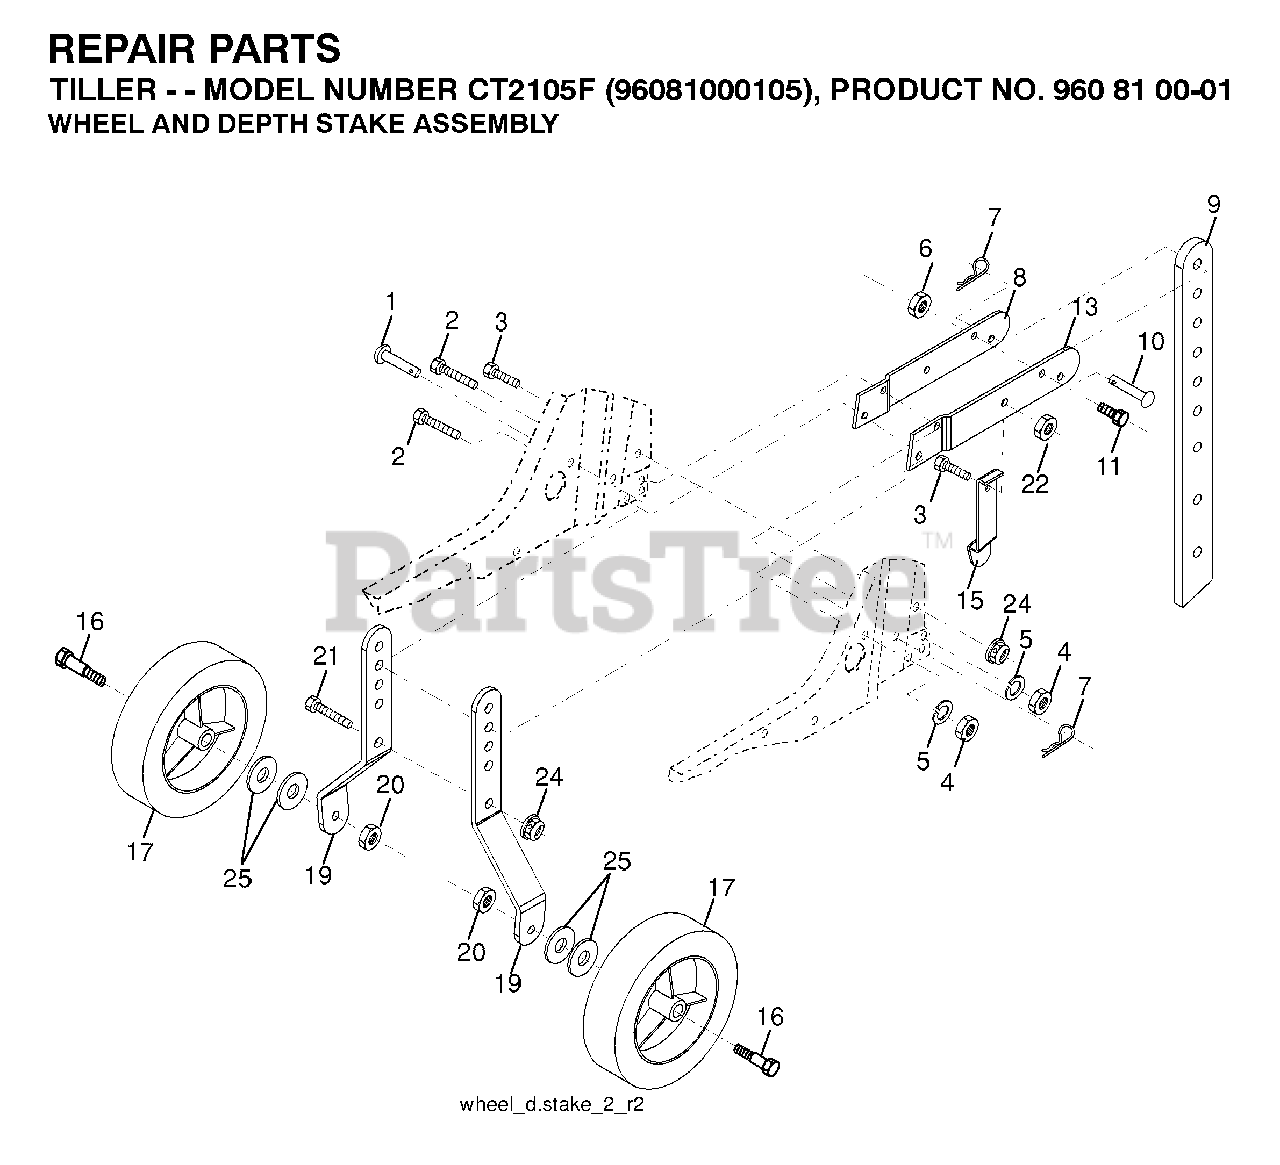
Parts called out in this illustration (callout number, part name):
1	PIN
2	BOLT
3	BOLT
5	LOCKWASHER
6	NUT
7	SPRING TI
8	SUPPORT.STAKE.RH.BLACK
9	RP STAKE.DEPTH.13.25.W/9HOLES
11	BOLT
16	BOLT.SHOULDER
17	WHEEL.8X1.75.STORM.GREY
20	LOCKNUT
21	BOLT RB
22	NUT.71038.31-18.HEX.NYLOCK
24	LOCKNUT-FLANGE 5/16-18
